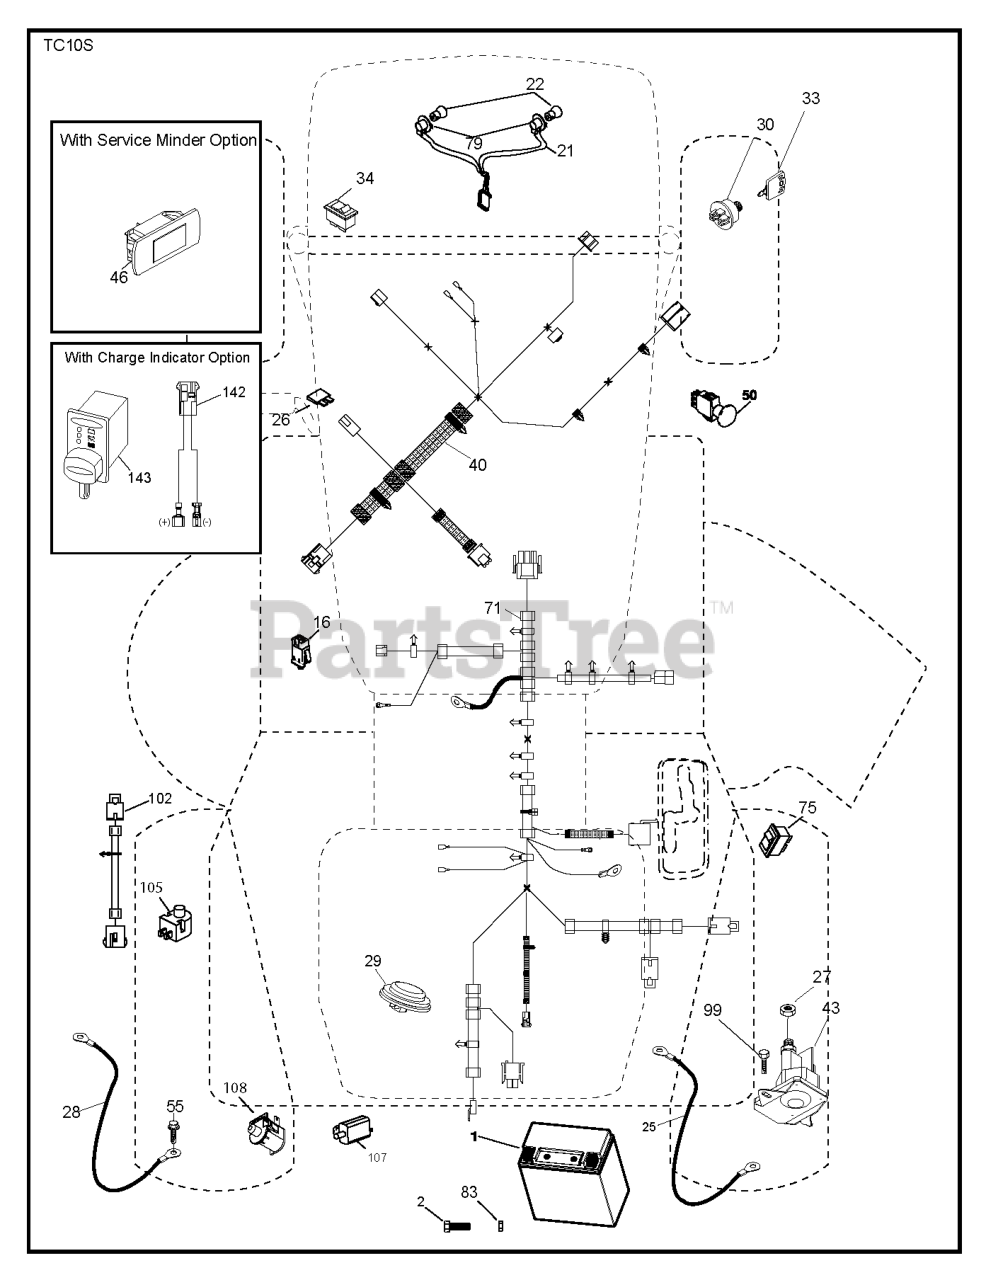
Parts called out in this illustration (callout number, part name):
1	BATTERY BATTERY 14AH 12V LEOC
2	SCREW.HEX.HEAD.CAP.M6 X1.12W
16	SWITCH INTERLOOK PUSH-IN
21	HARNESS.LIGHT W/4152J BULBS
25	CABLE CABLE.RED.20.8AWG.M6.CRD
26	FUSE 20AMP
27	NUT
28	CABLE CABLE.BLACK.20.8AWG.M6.C
29	SWITCH.SEAT.DELTA.OPC.
30	SWITCH.IGN.DELTA.W.LGH.ROS
33	KEY.CHAIN.BLISTER.PACK.GEN.USA
43	SOLENOID.W/BRASS.PLUNGER
46	RP.GUAGE.SRVCMNDR.HRMTR.
50	RP.PTO.SWITCH.8 TERMINAL.BLACK
55	SCREW 5/16"
71	HARNESS.CH.TCRD.HYD.TWIN.ELD
75	SWITCH.BAG.DUMP
79	BULB HOLDER ASM.
83	NUT NUT SQUARE
99	SCREW
102	HARNESS ASSY
105	REVERSE SWITCH
107	.WITCH.FULL BAGGER.INDICATOR
108	SWITCH.SNAPMOUNT.NC
142	CHARGE.PORT.PIGTAIL HARNESS
143	CHARGE.PORT
